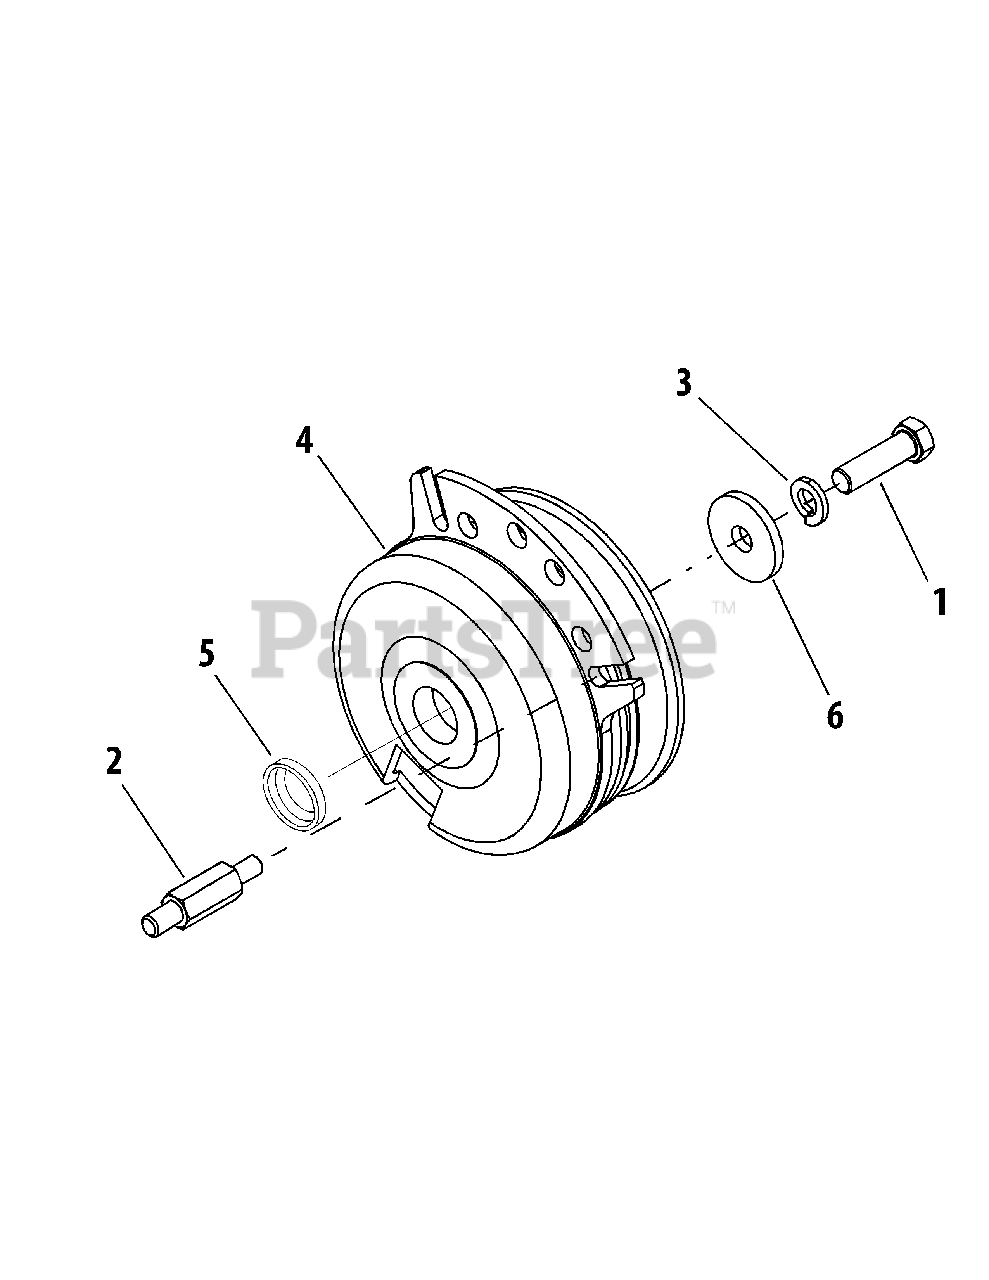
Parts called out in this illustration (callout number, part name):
1	Screw, Hex Cap, 7/16-20 x 1.5 GR5
2	Stud, Clutch Stop
3	Washer, Lock, 3/8
4	Clutch Assy, PTO
5	Spacer, 1.0 x 1.62 x .4
6	Washer, Flat, .445 x 1.5 x 1.72 Hdn
